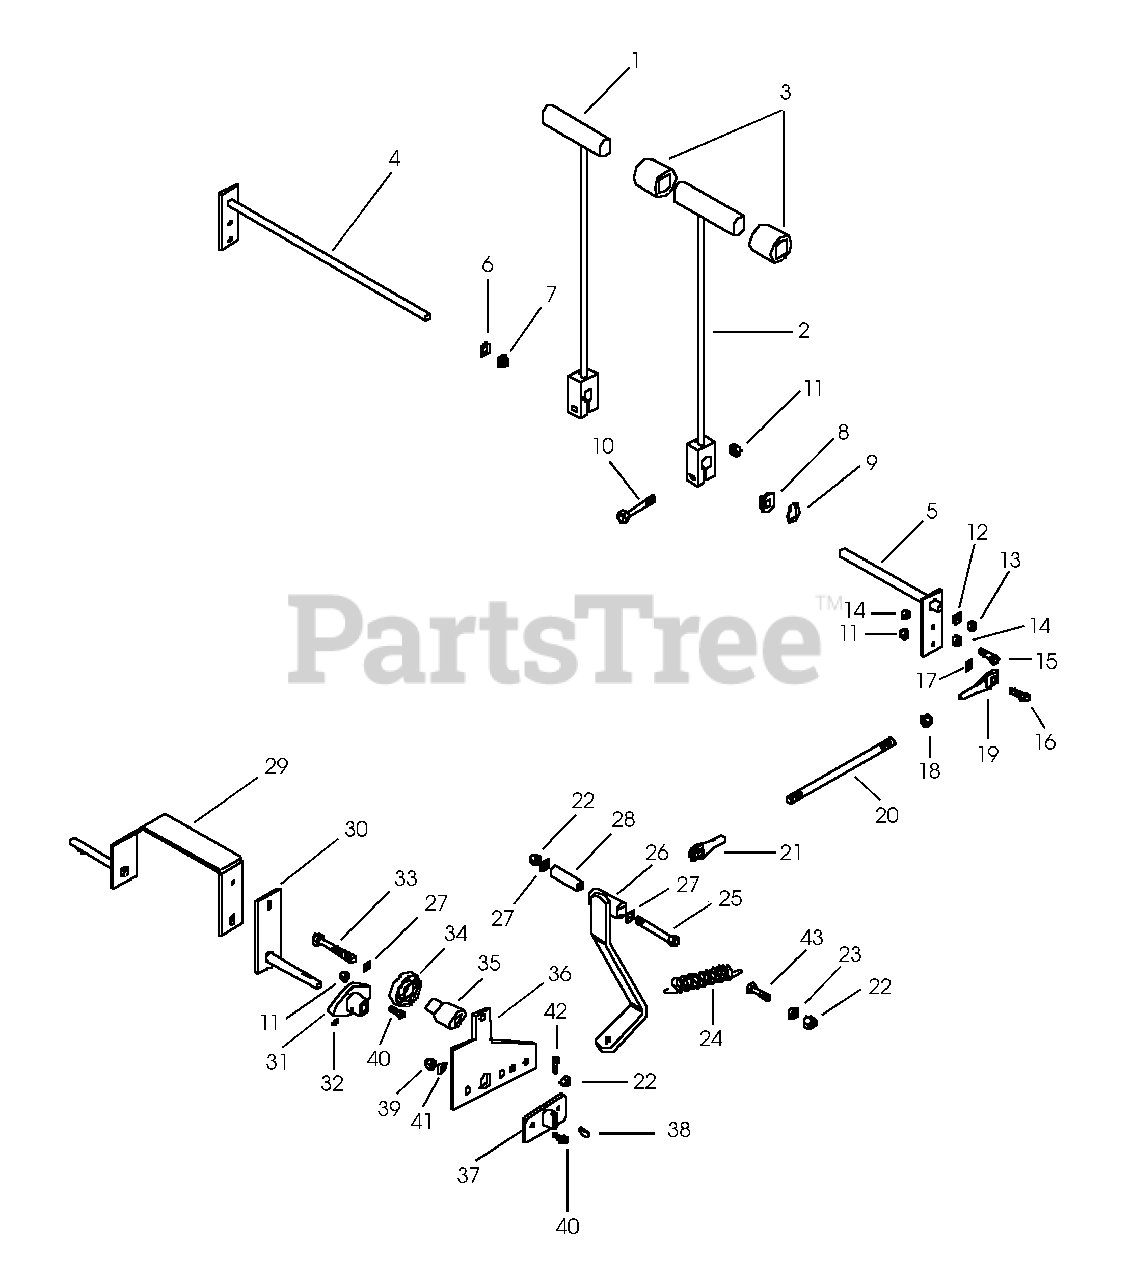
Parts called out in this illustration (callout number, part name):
1	Weldment-Steering Lever Left Hand
2	Weldment-Steering Lever Right Hand
3	Grip-T-Bar
4	Weldment-Steering Left Hand
5	Weldment-Steering Tube Right Hand
6	Ring-Retaining-External .500 x .460
7	Bushing-Flange .515 x .750 x .745 x 1.00
8	Bushing-Flange .762 x 1.0 x .580 x 1.48
9	Ring-Retaining-External .689 x .077
10	Bolt-Hex .31-18 x 1.50 Grade 5
11	Nut-Locking-Center .31-18
12	Washer-Flat-Steel .531 x 1.06 x .095
13	Nut-Locking-Center .50-13
14	Nut-Hex .31-18
15	Screw-Set .32-18 x 1.50
16	Bolt-Hex .31-18 x 1.25 Grade 5
17	Washer-Flat-Steel .344 x .688 x .065
18	Nut-Jam Left-Hand .375-24
19	Rod End-5/16" Female
20	Rod-Steering Adjuster
21	Rod End-5/16-24 Left Hand Female
22	Nut-Locking-Center .375-16
23	Nut-Hex .375-16
24	Apring-Tension .063 x .62 x 2.75
25	Bolt-Hex .38-16 x 2.75 Grade 5
26	Weldment-Neutral Detent
27	Washer-Flat-Steel .406 x .812 x .065
28	Shaft-Jack
29	Weldment-Pump Control Right Hand
30	Weldment-Pump Control Left Hand
31	Bushing-Flanged
32	Fitting-Lube .25-28 x .256
33	Bolt-Hex .38-16 x 2.00 Grade 5
34	Bearing-Ball .500 x 1.375 x .437
35	Hub-Bearing Mount
36	Arm-Speed Control
37	Arm-Speed Control
38	Key-Woodruff .13 x .75
39	Nut-Locking-Center .250-20
40	Bolt-Hex .31-18 x 1.00 Grade 5
41	Washer-Flat-Steel .281 x .620 x .065
42	Bolt-Hex .25-20 x .50 Grade 5
43	Bolt-Hex .38-16 x 1.25 Grade 5
